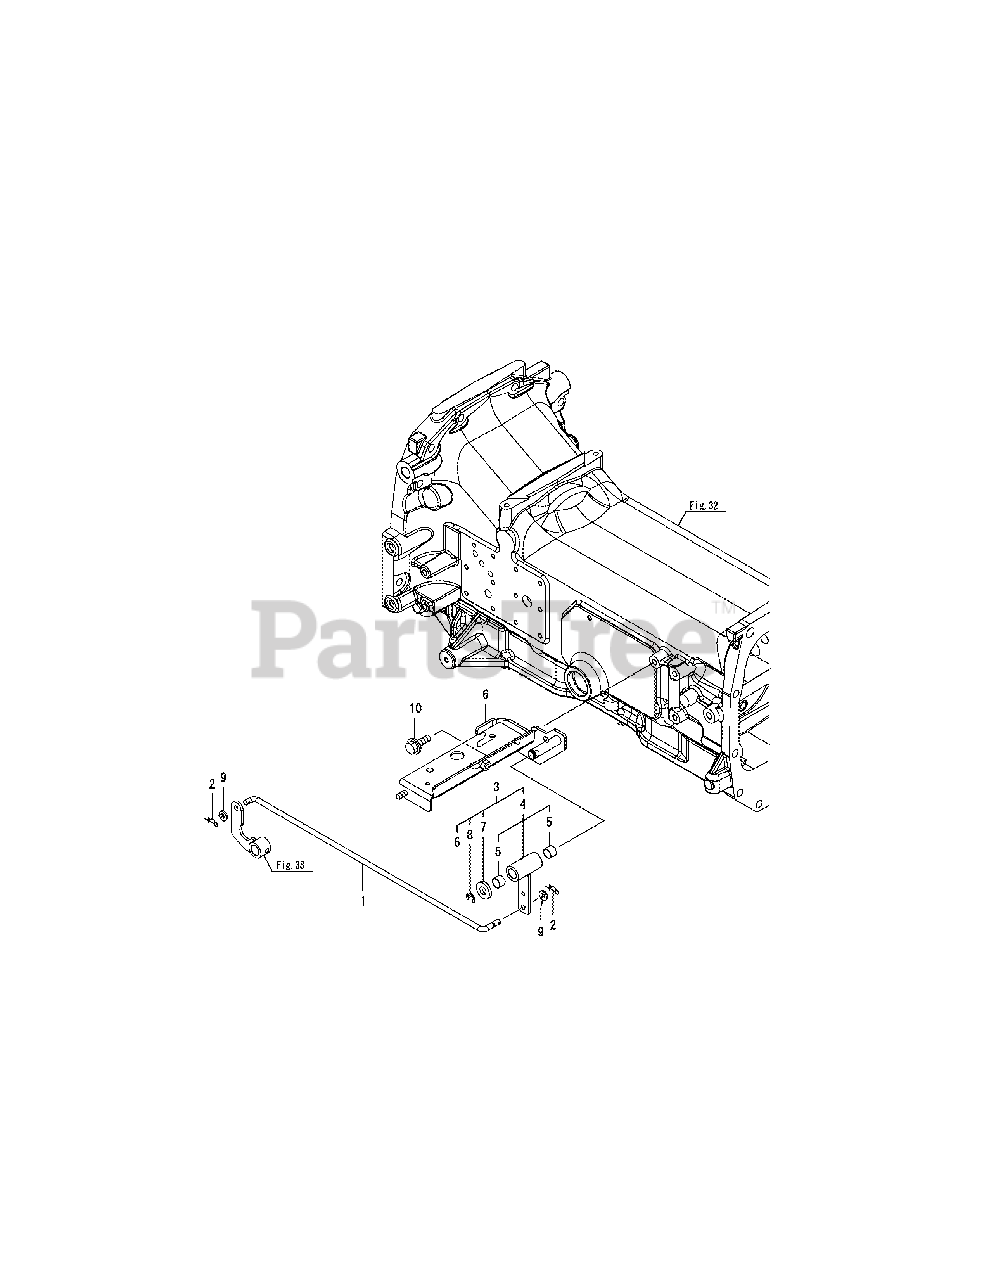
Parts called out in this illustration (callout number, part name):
2	PIN 8, COME-OFF SNAP
3	SUPPORT UNIT, REAR L
4	LINK, REVERSER ASSY
6	SUPPORT ASSY, REAR L
7	WASHER 14,POLISHED
9	WASHER 8, POLISHED
10	BOLT M10X 20 PLATED
